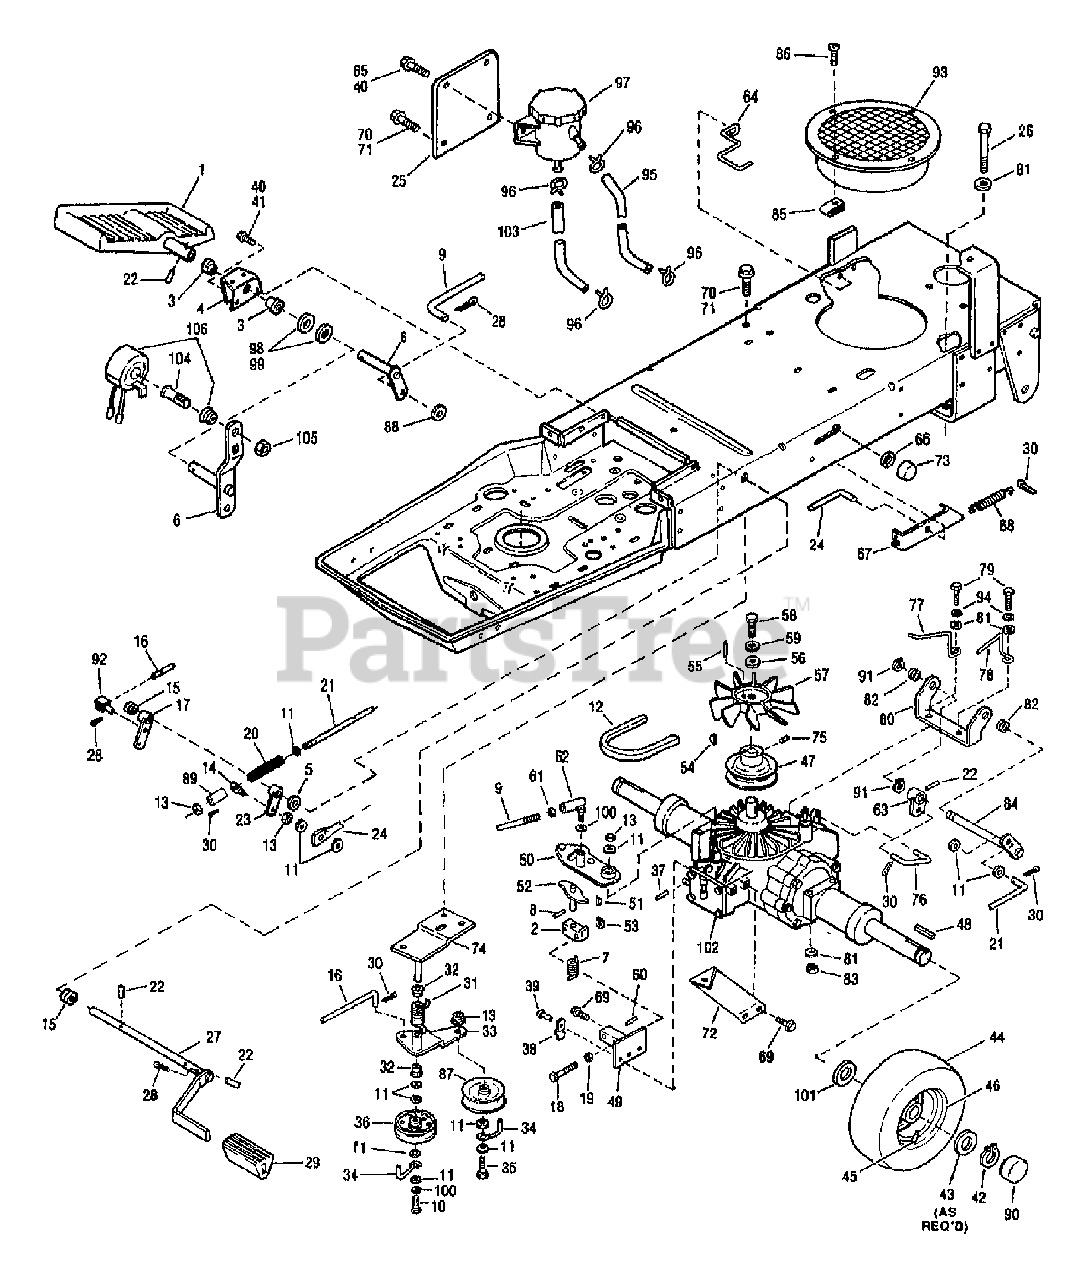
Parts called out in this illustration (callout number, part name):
2	BLOCK-PIVOT
3	BEARING-FLANGE
4	SUPT-HYD PEDAL
6	ASSM-CONTROL ARM
6	ASSM-CONT {3016HR,3016HRS}
7	SPRING-TORSION
8	PIN-ROLL .188X.75
9	ROD-SPEED CONTROL
13	NUT-LOCK 3/8-16
15	BUSHING-.68X.62X.15 FLNG
16	ROD-CLUTCH
17	ASSM-ARM
18	SCR-ADJUSTING
19	NUT-JAM
20	SPRING-COMP.
21	ROD-BRAKE
23	ASSM-ARM
24	ROD-BRAKE LOCK
27	ASSM-BRAKE PEDAL
29	FOOT REST
31	SPRING-TORSION
32	BELT-V
33	ASSM-IDLER ARM
34	GUIDE-BELT
38	LATCH
39	RIVET-POP
40	SCR-HH 1/4-20X.625
41	NUT-HF/LK 1/4-20 ZP
42	RING-RETAINING
43	WASHER-1.88X1.015X.06 ZP
45	STEM-VALVE
46	WHEEL-REAR
47	SHEAVE-HYDRO
49	ASSM-ADJUSTOR BLOCK
50	ASSM-SPEED CONT ARM
52	ASSM-PIVOT SHAFT
53	RING-RET.EXT .375 ID
56	WASHER-1.0X.281X.179 ZP
57	FAN-HYDRO TRANSMISSION
60	PIN-DOWEL .375 X 2.51
62	JOINT-BALL
63	ASSM-BRAKE ARM
64	GUIDE
65	NUT-HT LK 1/4-20
66	WASHER-FLAT
67	BRACKET-INTERLOCK
67	BRKT {3016HR,3016HRS}
68	SPRING
69	SCR-HFLK 5/16-18X.50 ZP
70	SCR-LOCK
71	NUT-HFLK 5/16-18 ZP
72	BRACE-TRANSAXLE
73	CAP-PUSH ON
74	ASSM-LEVER SUPP
75	SCR-SET 1/4-28X.38 HXSKT
76	BRAKE-LINK
77	GUIDE-BELT
78	GUIDE-BELT
80	SUPPORT-SHAFT
82	BEARING-FLANGED
83	NUT-TOP/LK 5/16-18 ZP
84	ASSM-JACKSHAFT
85	NUT-SPEED
87	PULLEY-IDLER
89	SPACER-.62X.406X.56 ZP
90	CAP-WHEEL
91	RING-RETAINING
92	PIVOT
93	SHROUD-FAN
95	HOSE-FUEL 18"
96	CLAMP-HOSE
97	ASSM-OIL RESERVOIR
98	WASHER-1.0X.64X.029
99	WASHER-1.0X.64X.09
101	SHIM-1.25X1.01X.06
102	KIT-CONVERSION W/HYDRO
104	SCR-SPECIAL
105	NUT-WHIZ LOCK {3016HR,3016HRS}
106	ASSM-MAGNET {3016HR,3016HRS}
